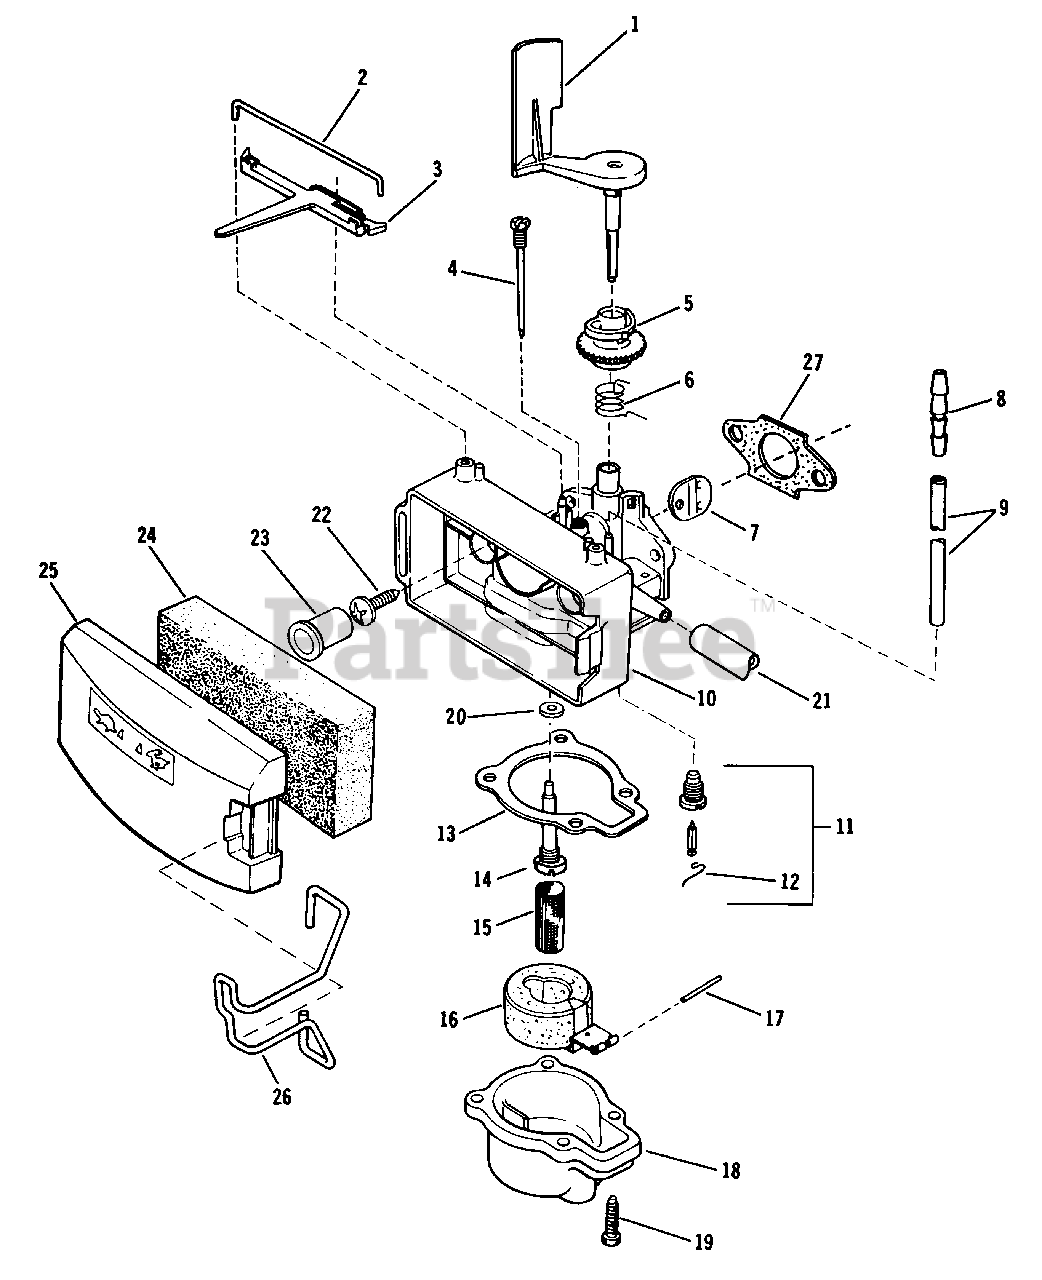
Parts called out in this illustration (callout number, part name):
1	Air Vane and Shaft
2	Retainer-Speed Control Lever
3	Speed Control Lever
4	Needle Adj. Assembly
5	Collar
6	Spring
7	Disc-Throttle
8	Connector-Reducer
9	Primer Tubing
10	Carburetor Body
11	Float Valve and Seat Assembly
12	Clip
13	Gasket
14	Nozzle Kit
15	Filter-Carburetor
16	Float and Arm Assembly
17	Pin-Float
18	Float Chamber
19	Screw-Float Chamber
20	Washer-Nozzle
21	Fuel Line
22	Screw-Carburetor Mounting
23	Plug
24	Element-Air Filter
25	Cover-Air Filter
26	Retainer-Filter Cover
27	Gasket-Carb. to C'case Cover
